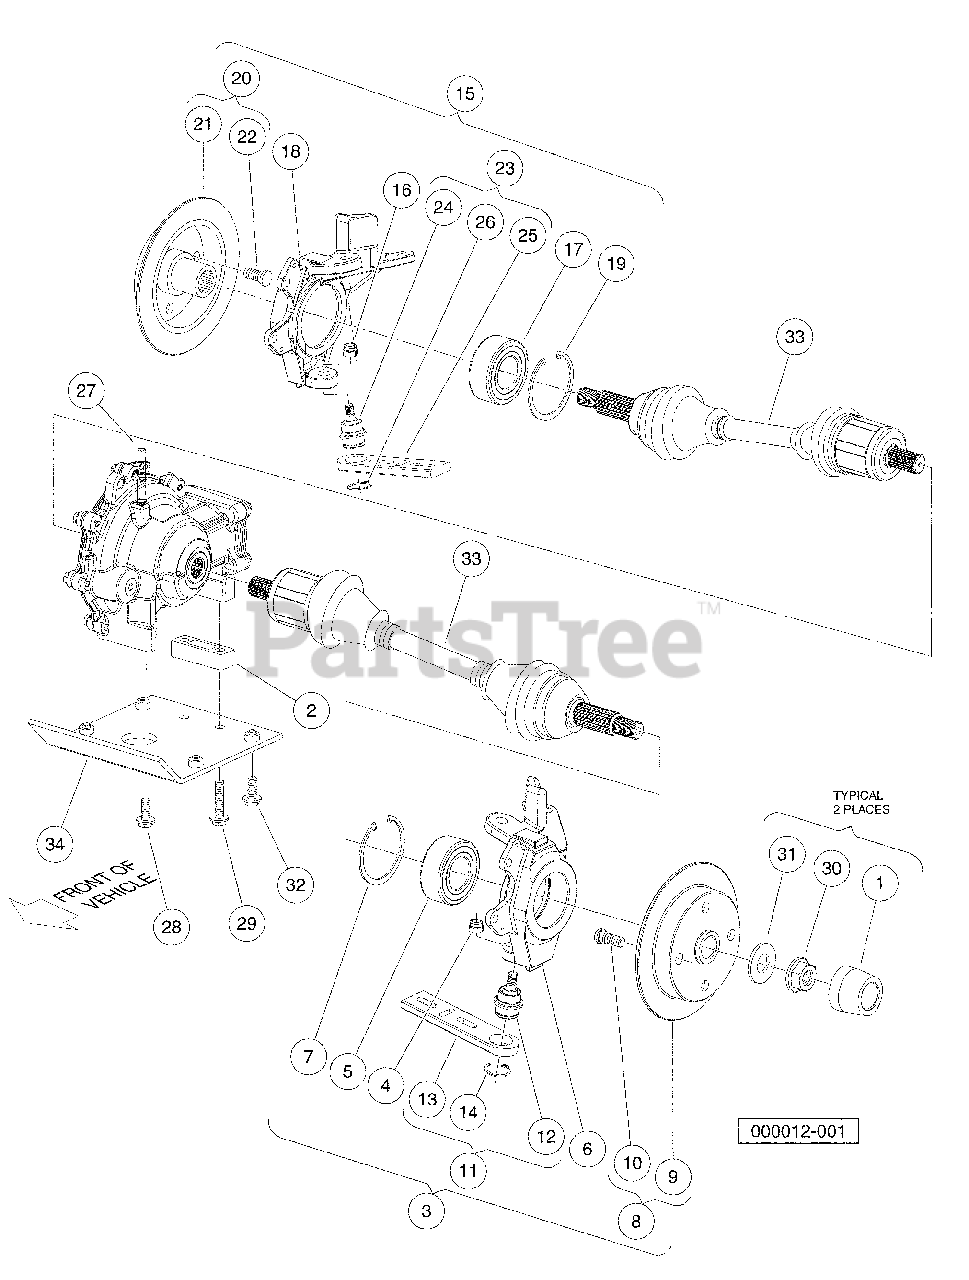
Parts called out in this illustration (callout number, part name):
1	Center Cap, Rubber
2	Spacer Block, Diff
3	Upright Sub-Assembly, LH
4	Locknut, M12-1.25 Nylon
6	Upright, Left
7	Internal Retaining Ring, 80mm Bore
8	Assy, Rotor, Brake, Front
9	Rotor, Brake, Front
10	Stud, Wheel Lug
11	Asm, Adjuster, Slide
12	Joint, Ball
13	Slide, Adjuster
14	Ring, Retaining, Ext, 1-1/4"
15	Upright Sub-Assembly, RH
16	Locknut, M12-1.25 Nylon
18	Upright, Right
19	Internal Retaining Ring, 80mm Bore
20	Assy, Rotor, Brake, Front
21	Rotor, Brake, Front
22	Stud, Wheel Lug
23	Asm, Adjuster, Slide
24	Joint, Ball
25	Slide, Adjuster
26	Ring, Retaining, Ext, 1-1/4"
27	Hose, Vent, Front Diff
28	Bolt Flanged Head, 3/8-16x1.0 with Loctite
29	Bolt Flanged Head, 3/8-16x1.500 with Loctite
30	Nut Flg, M22 X 1.5 Mech Def
31	Washer Hard, M22
32	Bolt, Flange Head, M10 X 1.5 X 25
33	Shaft, Half
34	Asm, Mount, Diff Plate
